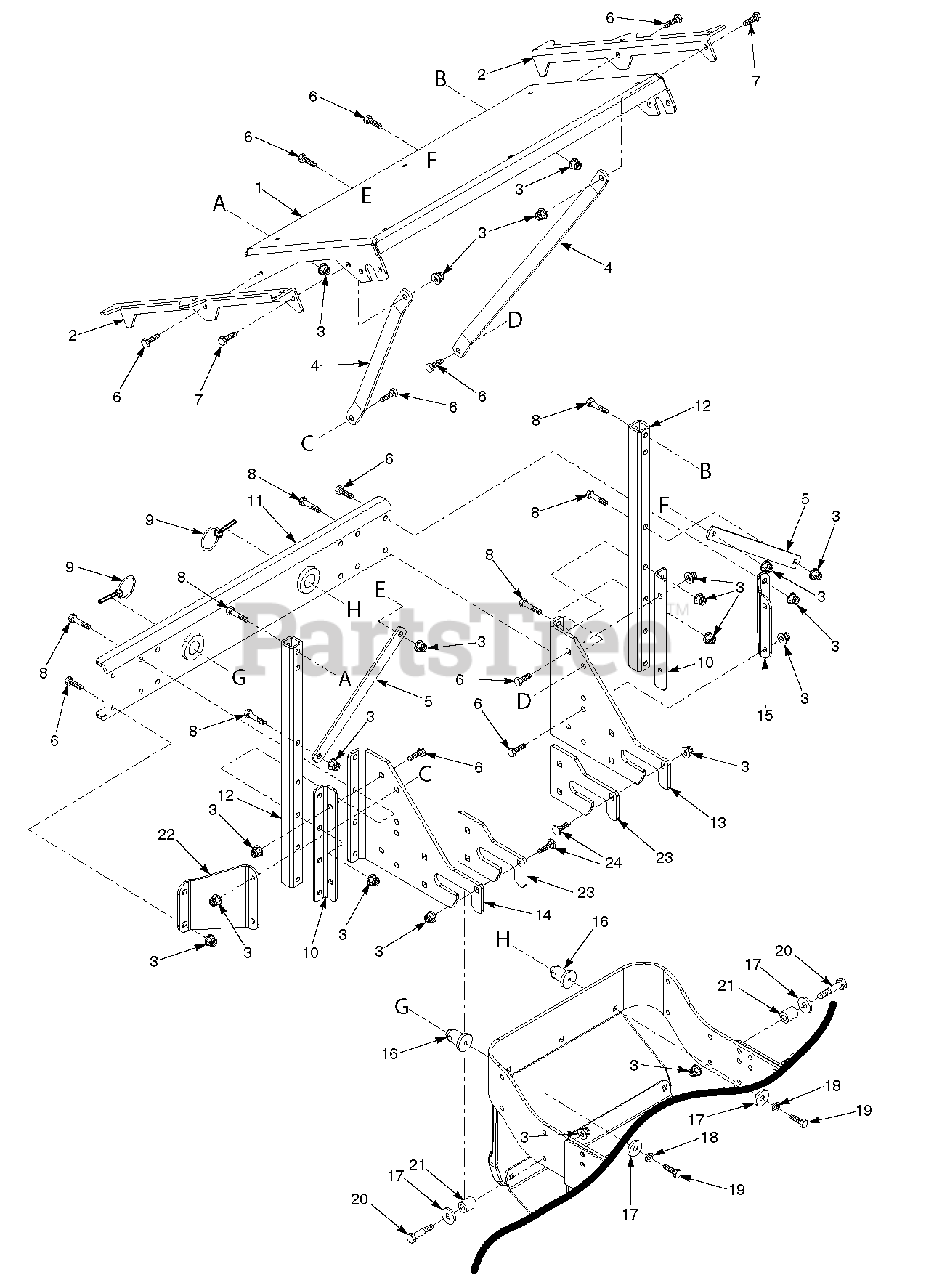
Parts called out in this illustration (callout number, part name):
1	Support Frame, Hopper
2	Bracket, Hopper Support
3	Nut, Elastic Flange 3/8-16
4	Brace, Stiffener
5	Brace, Engine Mount
6	Bolt, Hex Head 3/8-16 x 1"
7	Bolt, Hex Head 3/8-16 x 1-1/4"
8	Bolt, Hex Head 3/8-16 x 2-1/4"
9	Quick Pin
10	Mounting Bracket, Tube
11	Mounting Bracket Weldment
12	Tube, Upright
13	Mounting Bracket, GC R.H.
14	Mounting Bracket, GC L.H.
15	Angle Bracket, GC
16	Pin, GC Locator
17	Flatwasher, 3/8-.406 x 1.50 x 7 Ga.
18	Lockwasher, 3/8"
19	Bolt, Hex Head 3/8-16 x 1-1/4"
20	Bolt, Hex Head 3/8-16 x 2-1/4"
21	Spacer
22	Angle Bracket, GC
23	Wear Plate, GC
24	Bolt, Carriage 3/8-16 x 1-1/4"
